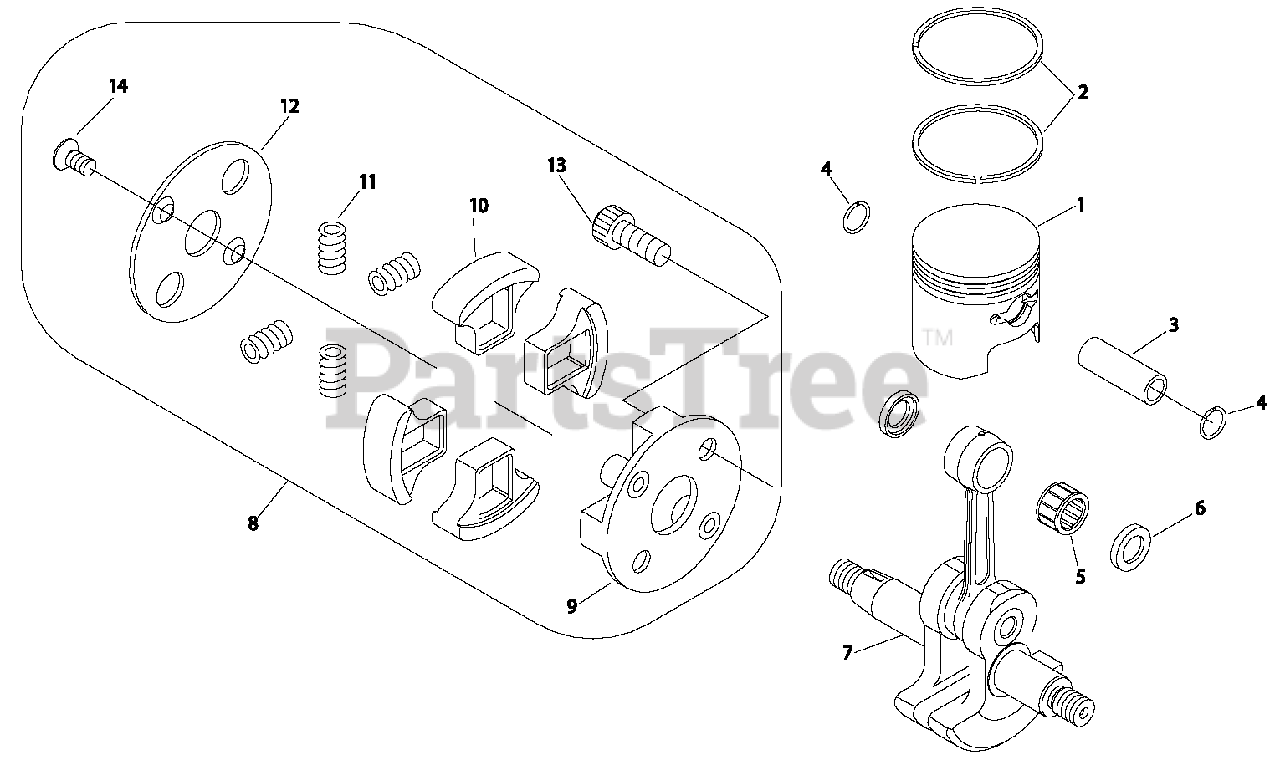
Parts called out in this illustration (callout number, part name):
1	PISTON
2	RING, PISTON
3	PIN, PISTON
4	RING, RETAINING
5	BEARING, NEEDLE - 10
6	SPACER, PISTON
7	CRANKSHAFT ASSY
8	CLUTCH ASSY
9	HUB, CLUTCH
10	SHOE, CLUTCH
11	SPRING, CLUTCH
12	PLATE, CLUTCH
13	BOLT, CLUTCH
14	SCREW
